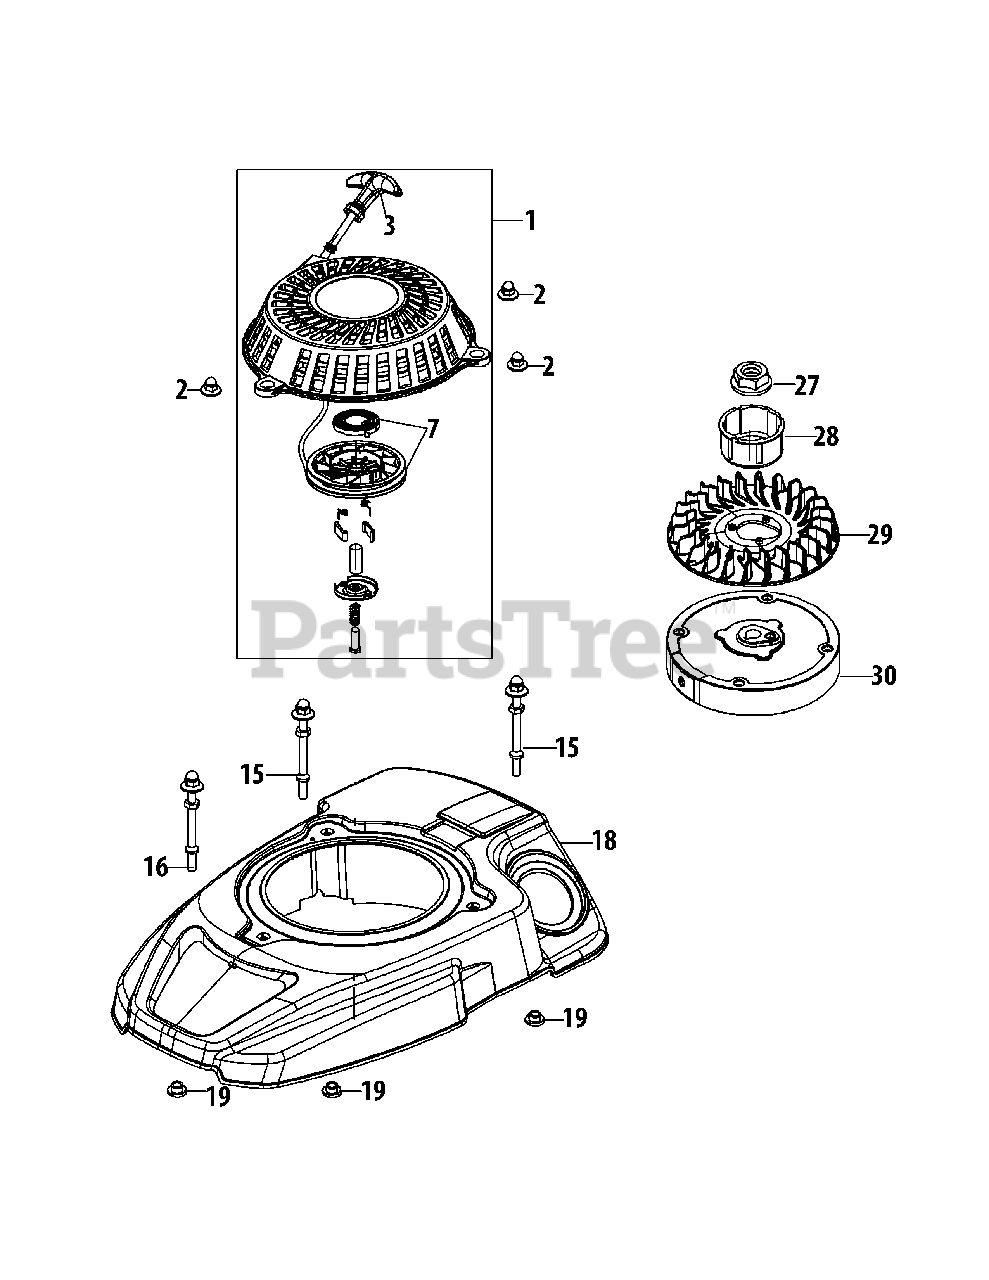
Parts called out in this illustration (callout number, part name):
1	Recoil Starter Assembly
2	Starter Acorn Nut
3	Starter Handle
7	Recoil Pulley & Spring Ass'Y
15	Starter/Shroud Rear Stud M6×78.5
16	Starter/Shroud Front Stud M6×74
18	Engine Shroud
19	Engine Shroud Spacer
27	Flywheel Nut M14
28	Starter Cup
29	Cooling Fan
